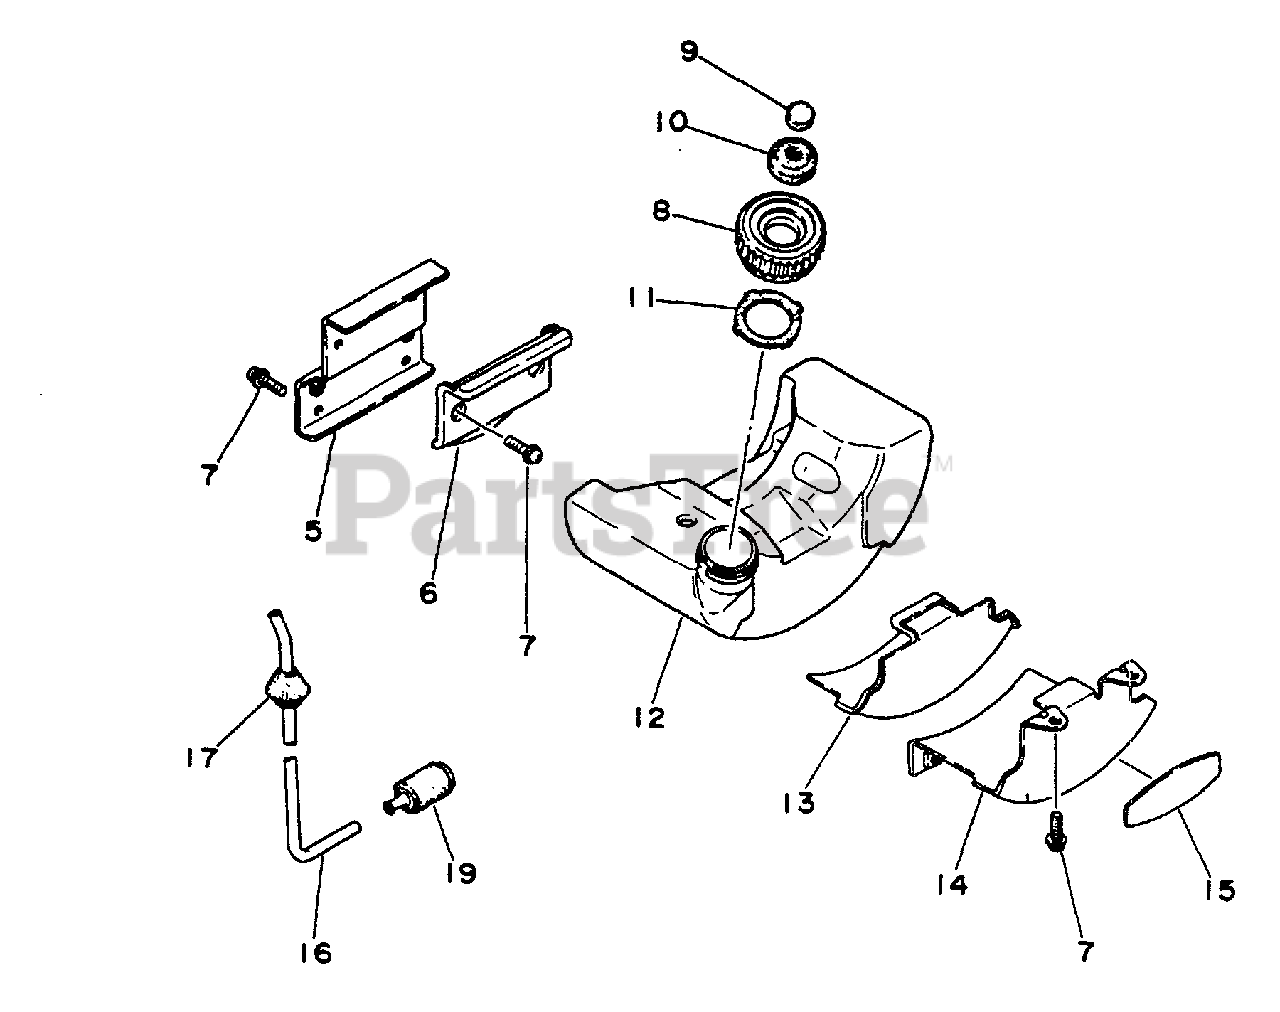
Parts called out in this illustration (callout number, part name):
5	BRACKET, FUEL TANK
6	CUSHION, FUEL TANK
7	SCREW - 4X14
8	CAP ASSY
11	GASKET, CAP
12	TANK, FUEL
14	BRACKET, FUEL TANK
15	LABEL - ECHO
16	PIPE, FUEL - 3X6X135
19	FILTER, FUEL
